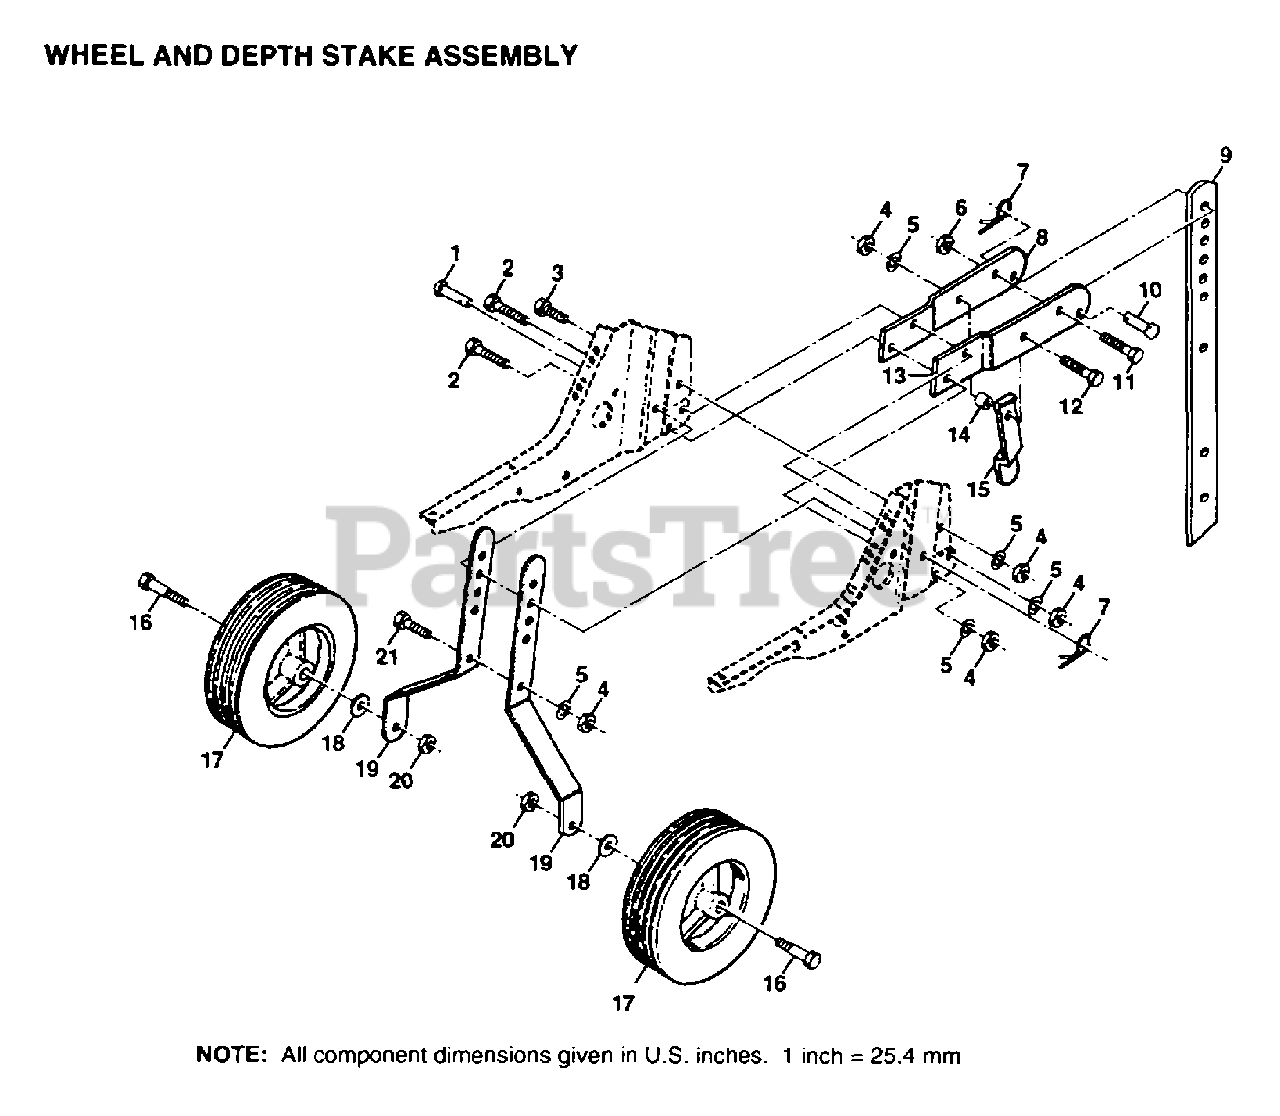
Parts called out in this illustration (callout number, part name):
1	DRILLED RIVET RT
3	BOLT
4	NUT.HEX.5/16-18
5	LOCKWASHER
6	GRIPCO NUT
7	SPRING.RETAINER
11	BOLT.3/8-24X1-1/2
12	BOLT.HEX.5/16-1.5
14	WASHER
15	STAKE SPRING TI
16	BOLT SHOULDER
18	WASHER
